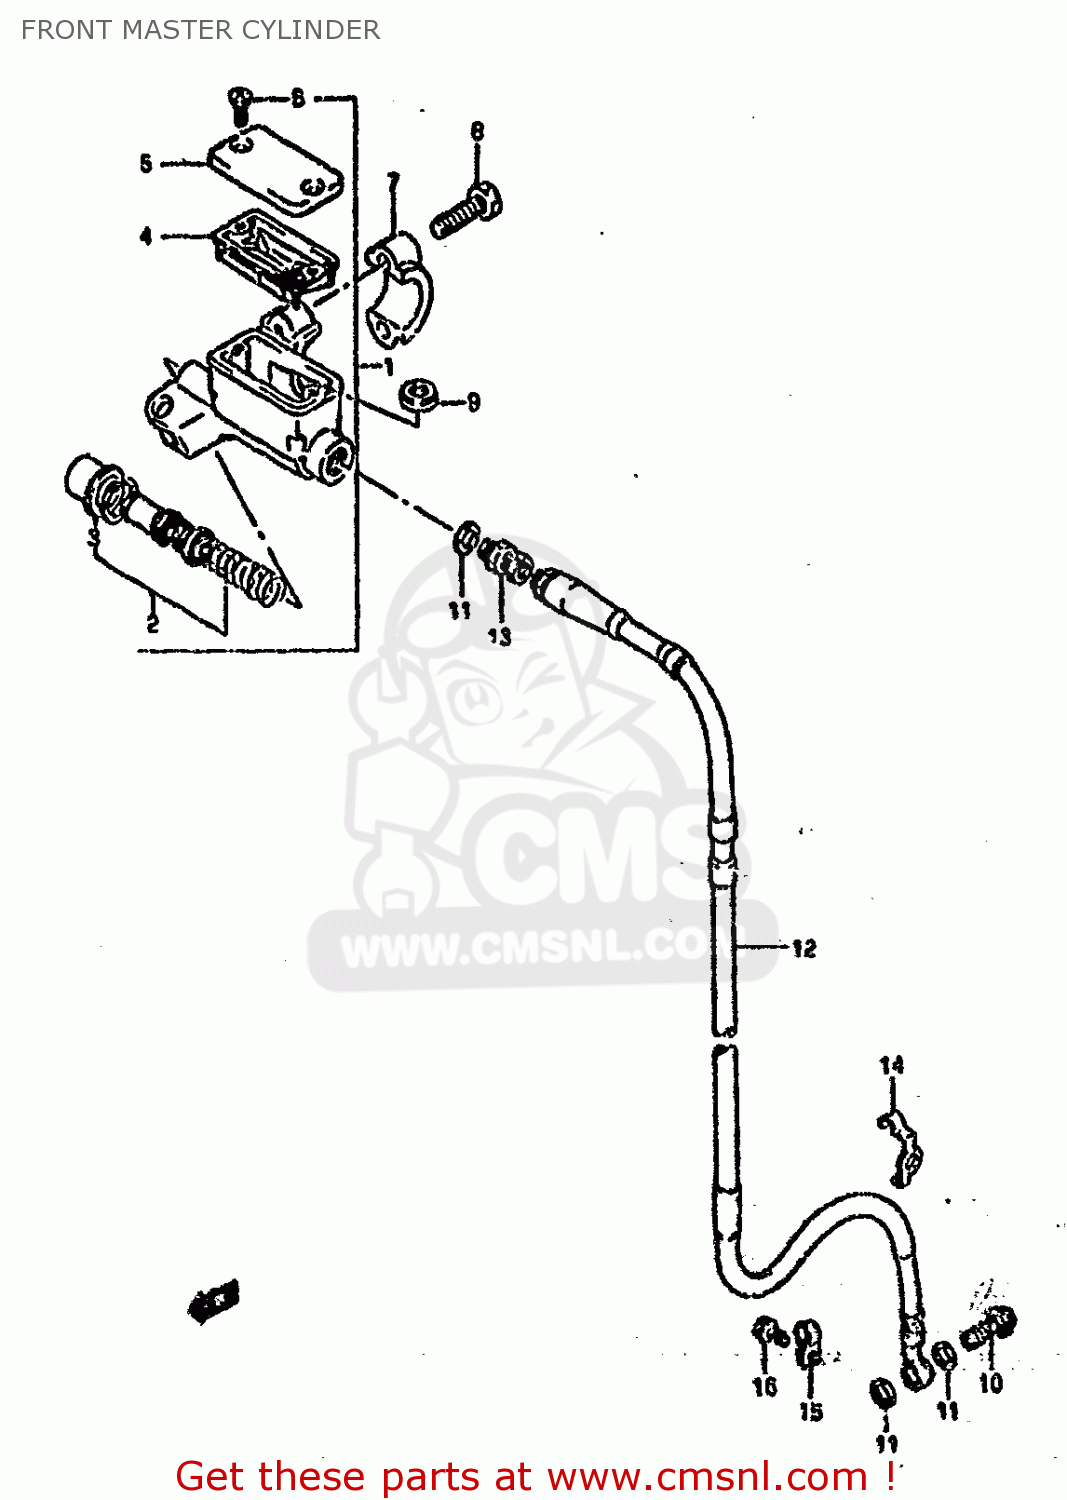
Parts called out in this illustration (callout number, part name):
1	CYLINDER ASSY,FR MASTER
2	PISTON & CUP SET
3	BOOT
4	DIAPHRAGM
5	CAP
6	SCREW
7	HOLDER
8	BOLT
9	SEPARATOR
10	BOLT UNION
11	WASHER(10X15X1.5)
12	HOSE,FR BRAKE
13	ADAPTOR,BRAKE HOSE
14	CLAMP,FRONT BRAKE HOSE
15	CLAMP,FR BRAKE HOSE NO.2
16	BOLT
